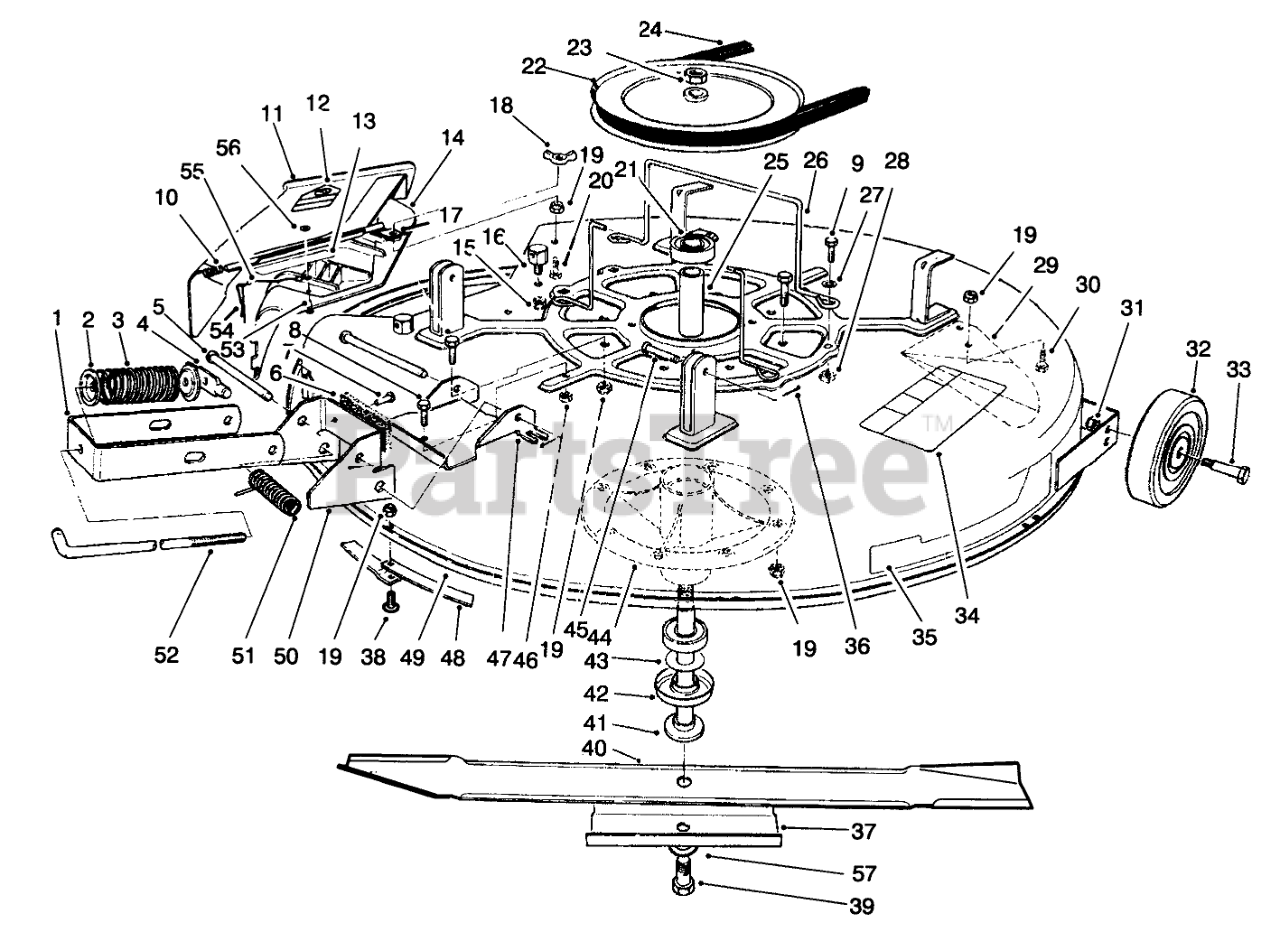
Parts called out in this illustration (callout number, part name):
1	Bracket-Engagement
2	RETAINER-SPR. TOP
3	SPRING-COMPRESSION
4	SHAFT-DECK ADJ.
5	PIN-CLEVIS
6	PAD-BRAKE
7	RIVET-BLIND
8	SCREW-HH
9	SCREW-HH
10	SPRING
11	Assembly-Deflector (Incl. Ref. #12)
12	DECAL-DANGER
13	DECAL-DANGER, DEFLECTOR
14	Assy.-Cover, Discharge (Incl. Ref. #53-56)
15	NUT-LOCK, NI
16	POST-PIVOT
17	Brace-Cover, Rear
18	NUT-WING
19	NUT-LOCK, NI
20	SCREW-HH
21	BEARING-BALL
22	PULLEY
23	NUT-HEX
24	V-BELT, DECK
25	SPACER-BEARING
26	GUIDE-BELT
27	WASHER-PLAIN
28	NUT-RETAINER
29	Kicker
30	SCREW-HH
31	NUT-LOCK, NI
32	WHEEL-DECK
33	BOLT-WHEEL
34	DECAL-DANGER, THROWN OBJECT
35	DECAL - RECYCLER 32"
36	PIN-COTTER
37	STIFFENER
38	SCREW-PPH
39	SCREW-HH
40	BLADE-RECYCLER
41	SHAFT-SPINDLE
42	SHIELD-BEARING
43	SPACER-HARDNED
44	SPINDLE
45	PIN-CLEVIS
46	NUT-HEX
47	Plate-Deck, Brake Mtg.
48	RING-DECK
49	Deck-Recycler (Incl. Ref. # 13, & 34)
50	Brake Ass-y (Incl. Ref. #6-7)
51	SPRING
52	ROD-ENGAGEMENT
53	RIVET-BLIND
54	PIN-LOCKING, CHUTE
55	LANYARD
56	WASHER-PLAIN
57	WASHER-BELLEVILLE
